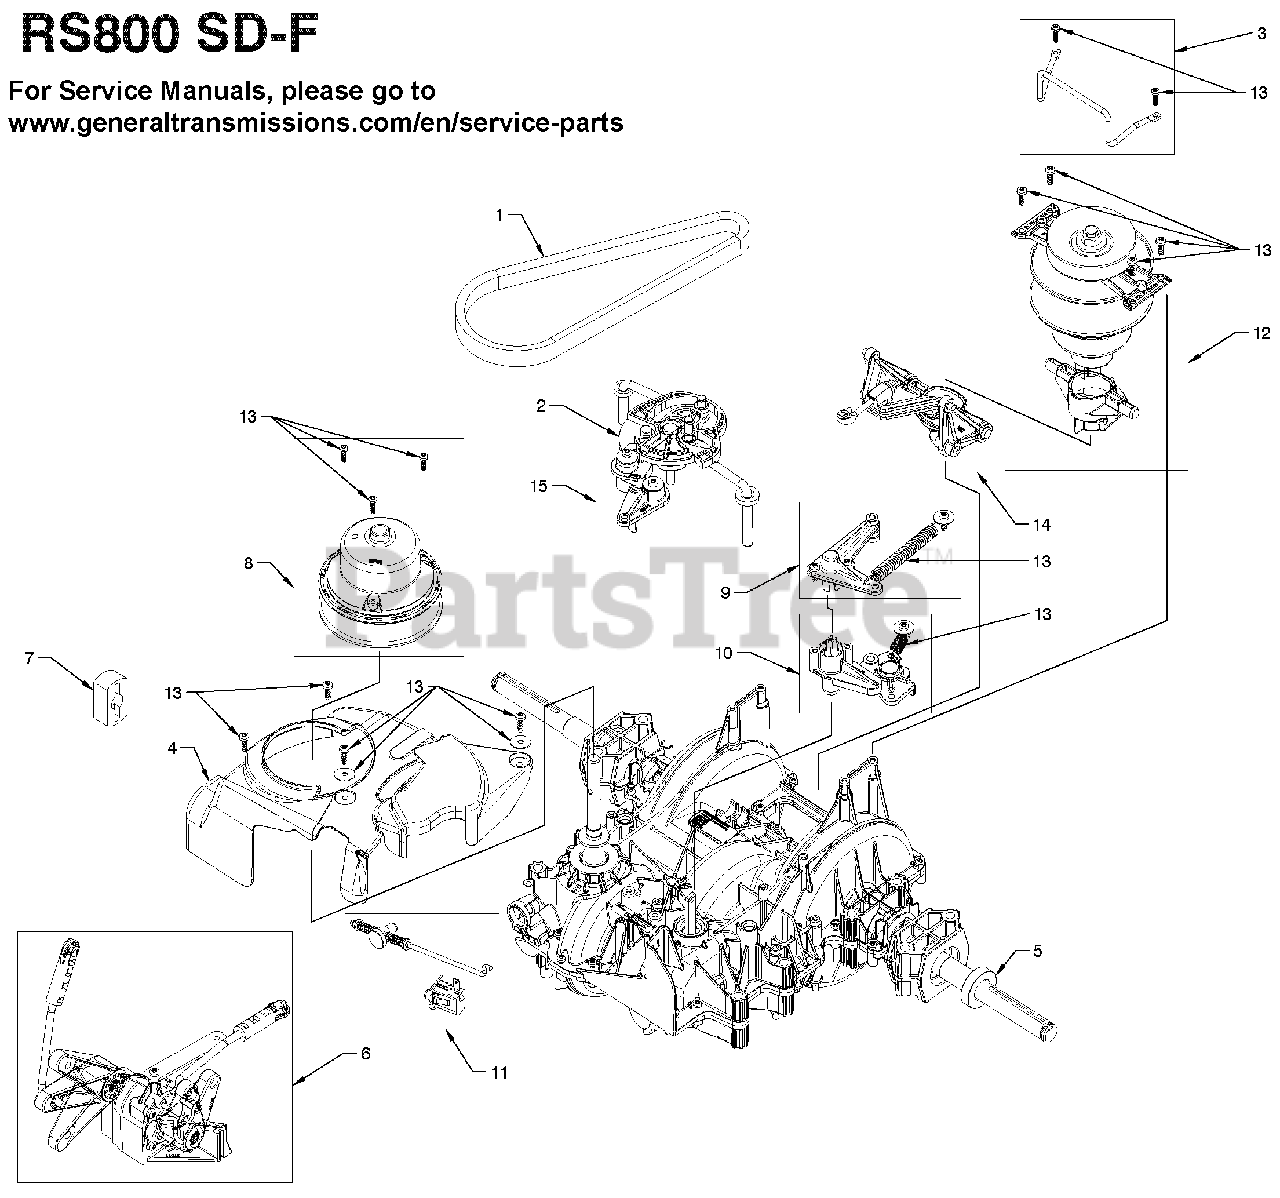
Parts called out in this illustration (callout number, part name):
1	VARIATION BELT
2	CONTROL CAM RS800 F
3	BELT KEEPER KIT
4	COVER RS800 F
5	OUTPUT SEAL (QTY 1)
6	FRICTION PACK
7	DRIVEN TOOL
8	DRIVEN KIT RS800
9	BRAKE KIT
10	BYPASS KIT
11	INVERSION KIT
12	DRIVER / ANTI DEBRIS KIT
13	HARDWARE KIT RS800
14	VARIATION KIT
15	CONTROLS KIT RS800 F
